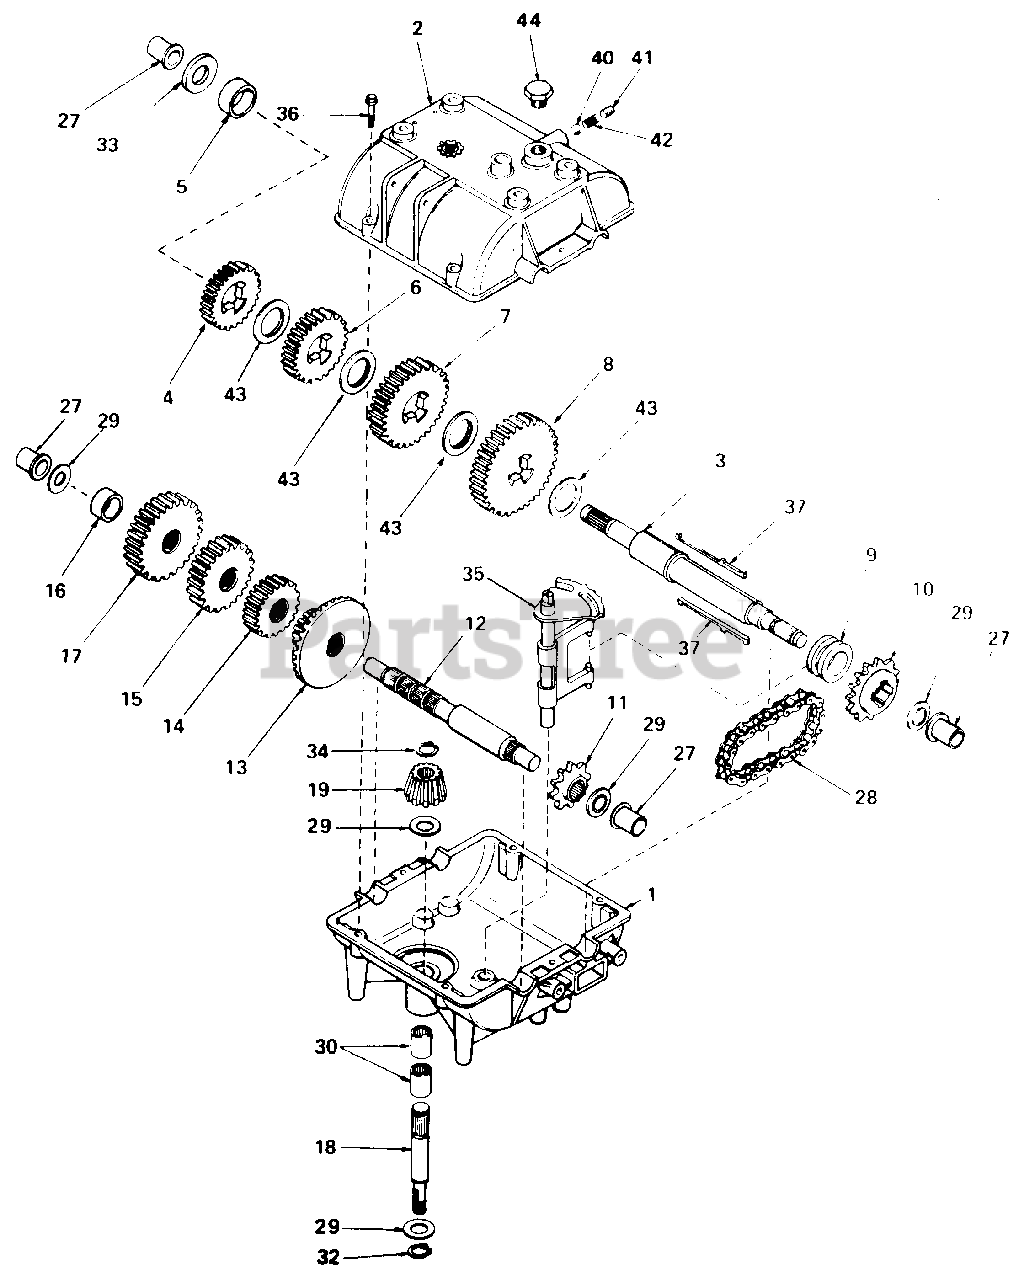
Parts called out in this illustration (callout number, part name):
1	Case, Transmission
2	Cover, Transmission
3	Shaft, Output & Brake
4	Gear, Spur (20 teeth)
6	Gear, Spur (25 teeth)
7	Gear, Spur (30 teeth)
8	Gear, Spur (35 teeth)
9	Collar, Shift
10	Sprocket (14 teeth)
11	Sprocket (10 teeth)
12	Shaft, Counter
13	Gear, Bevel (42 tooth & 15 tooth spur gear)
14	Gear, Spur (20 teeth)
15	Gear, Spur (25 teeth)
17	Gear, Spur (30 teeth)
18	Shaft, Input
19	Bevel Pinion, Input
27	Bushing, Flanged
28	Chain, Roller (No. 41 chain, 22 links)
29	Race, Thrust
30	Bearing, Needle
32	Ring, Retaining
34	Ring, Retaining
35	Rod & Fork Ass'y., Shift
36	Screw, Hex Hd. Taptite, 1/4-20 x 1/4
37	Key
40	Ball, Steel, 5/16"
41	Screw, Set, 3/8-16 x 3/8
42	Spring
43	Washer, Thrust
